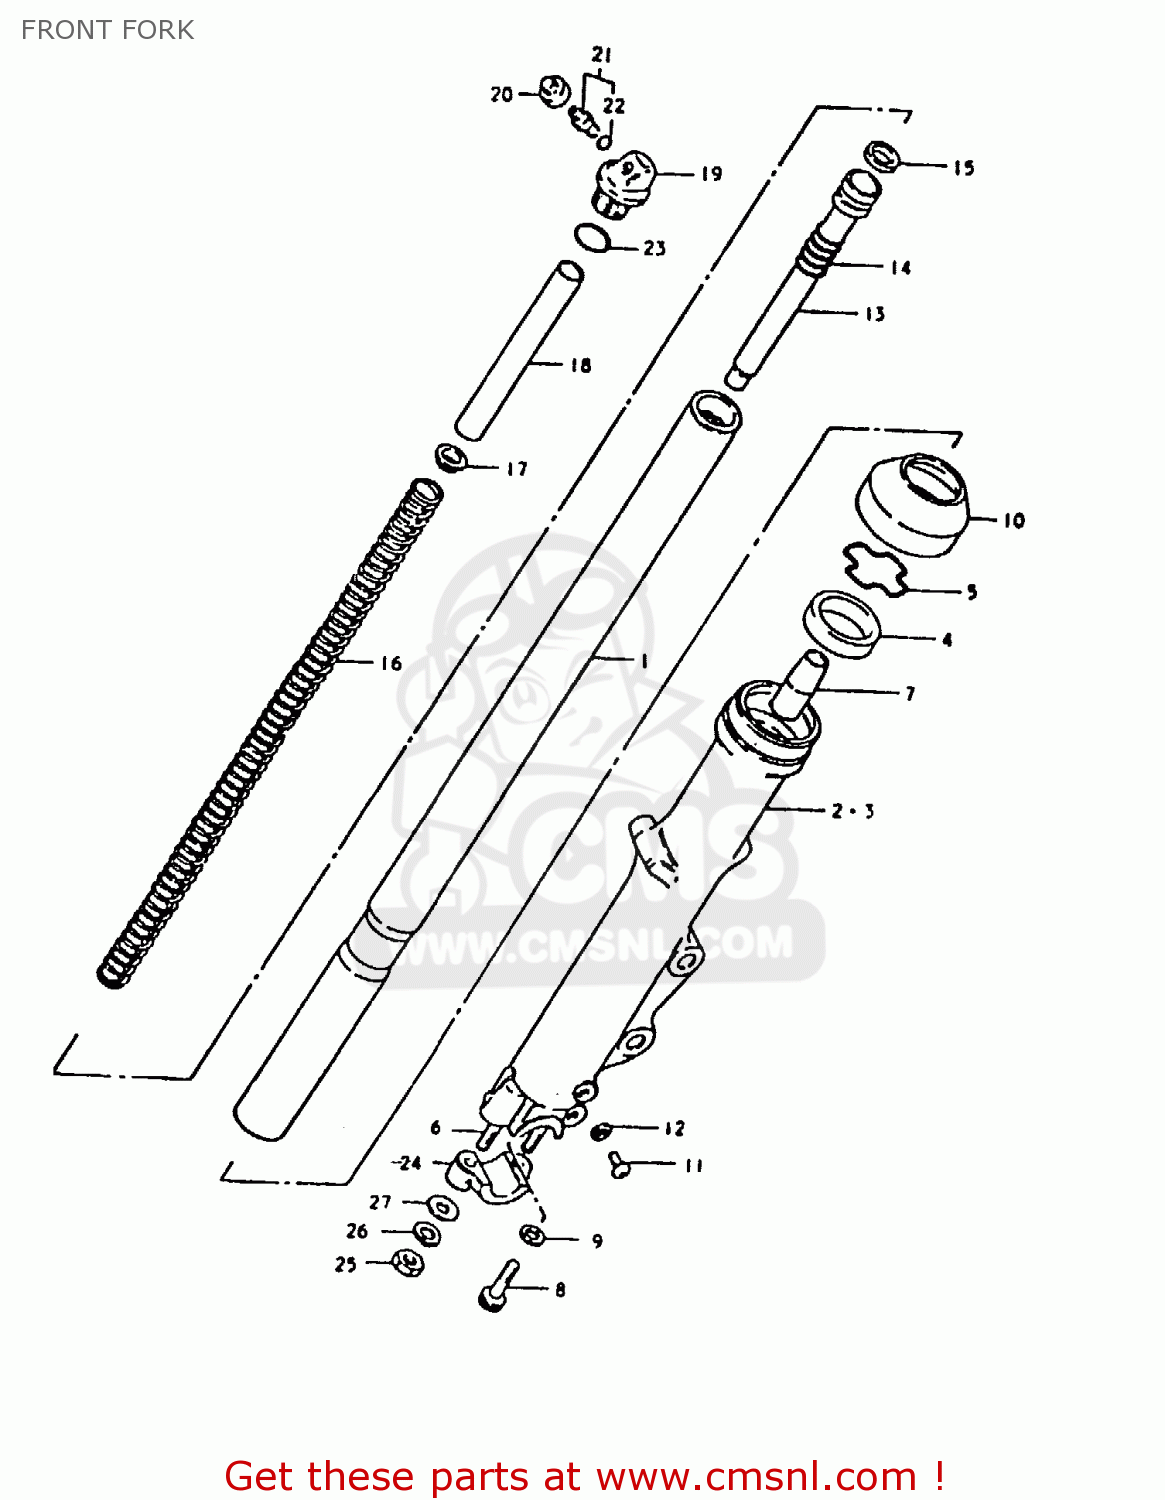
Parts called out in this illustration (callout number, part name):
1	TUBE,FORK,INNER
2	TUBE,FORK,OUTER,RIGHT
3	TUBE,OUTER,LEFT
4	OIL SEAL,FRONT FORK
5	RING,STOPPER
6	STUD BOLT
7	PIECE,OIL LOCK
8	BOLT,FORK CYLINDER(10X25)
9	GASKET (NAS)
10	SEAL,DUST
11	SCREW
12	GASKET,DRAIN,PLUG (NAS)
13	CYLINDER,FRONT FORK
14	SPRING,REBOUND
15	RING,PISTON
16	SPRING,FRONT FORK
17	GUIDE,FRONT FORK SPRING C
18	SPACER,FRONT FORK SPRING
19	CAP
20	CAP,VALVE
21	VALVE
22	O RING
23	O RING
24	HOLDER,AXLE
25	NUT (8MM)
26	LOCK WASHER
27	WASHER
